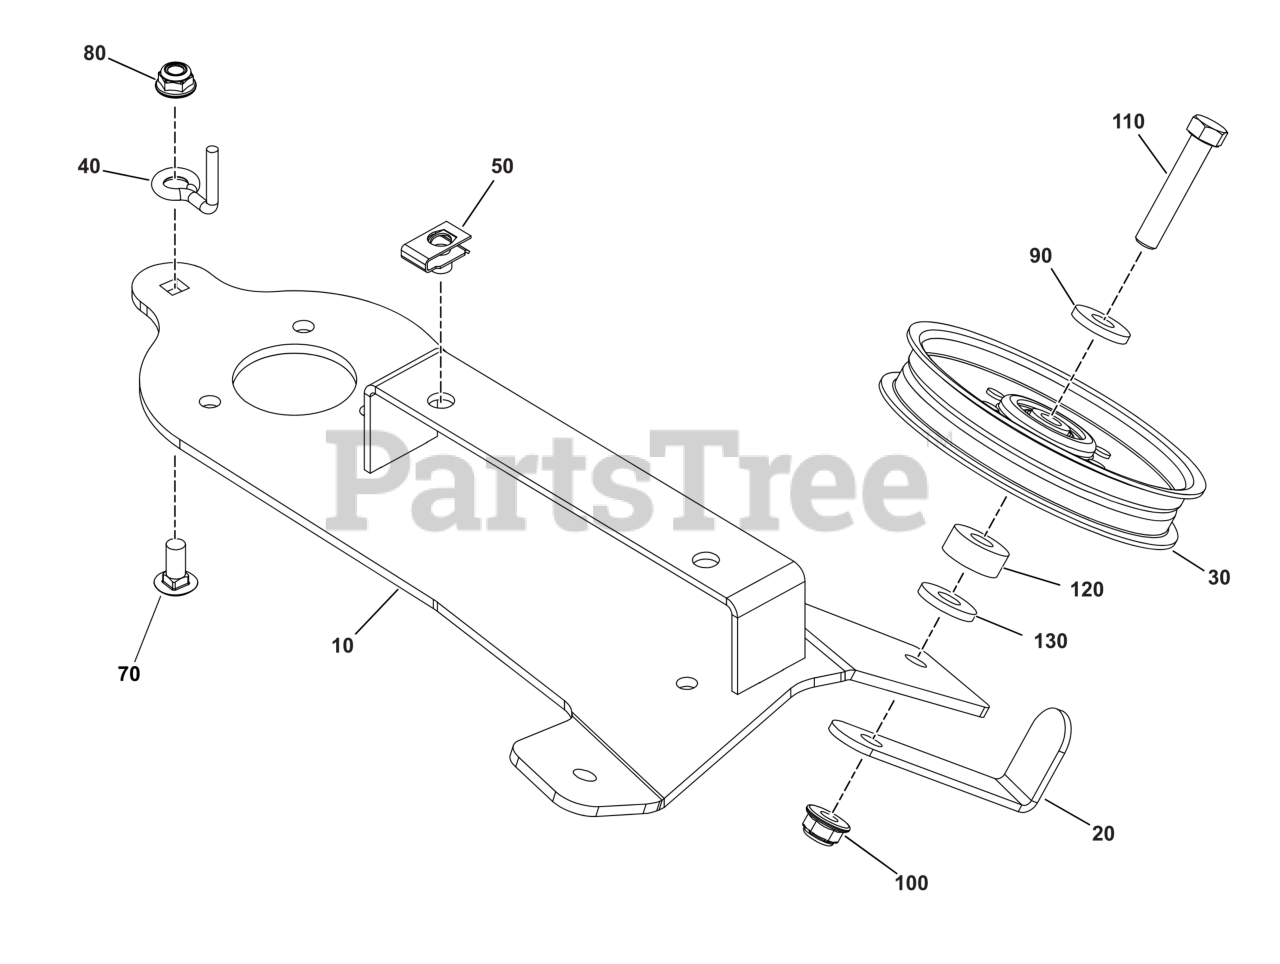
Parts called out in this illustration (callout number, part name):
10	WELD, PLATE ASSEMBLY, 61" TP - BLK
30	PULLEY, Idler
50	NUT, SPEED, 5/16-18 L
70	BOLT, 5/16-18 X 3/4",
80	NUT
90	WASHER
100	NUT, 3/8-16 HEX NYLOCK
110	CAPSCREW, 3/8-16X2
130	WASHER, 3/8" FENDER
